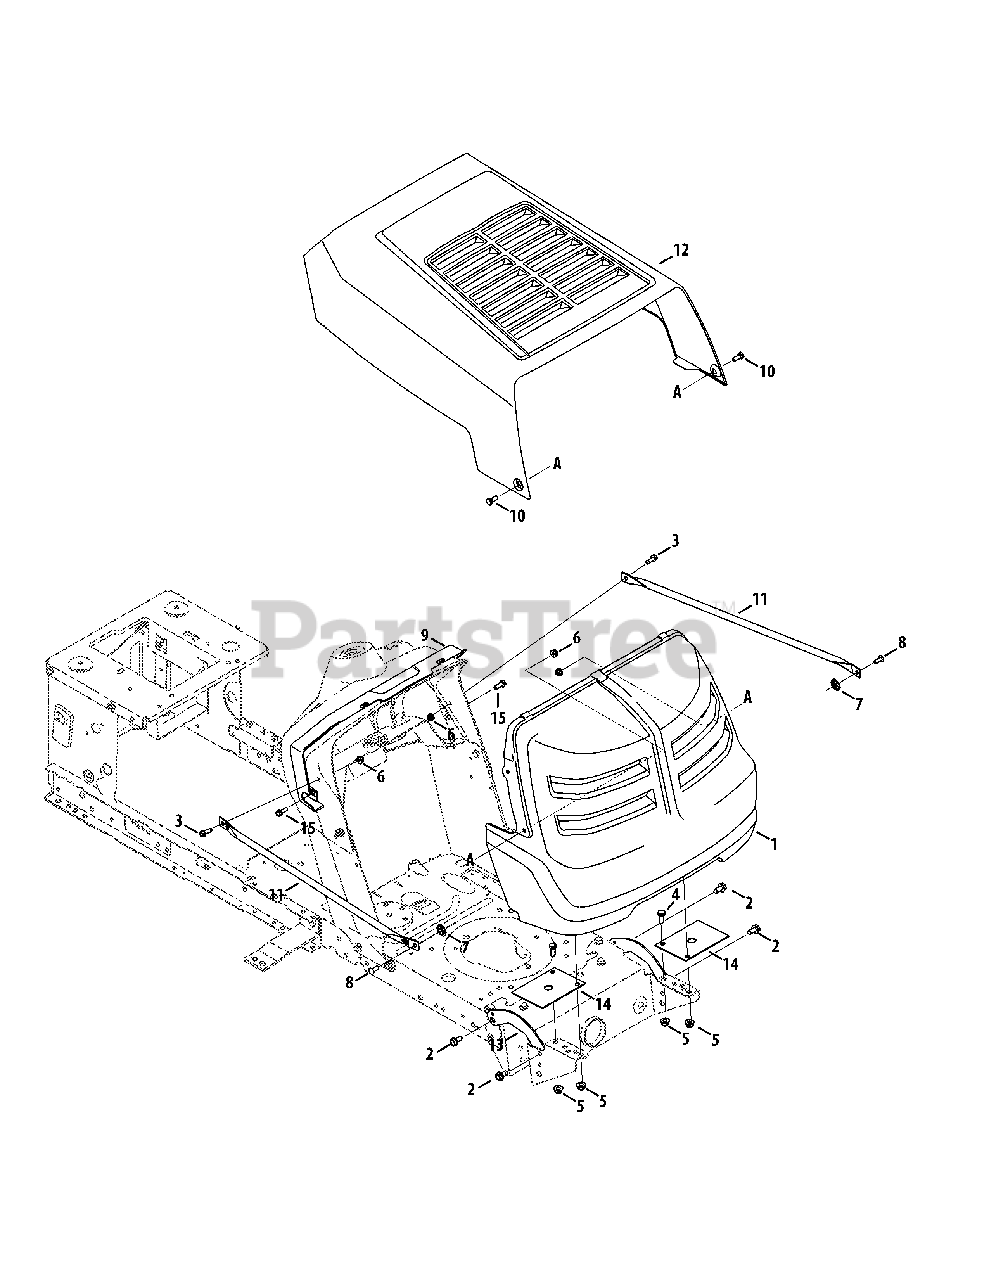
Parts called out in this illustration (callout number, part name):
1	Grill Assembly
2	Screw, Tap, 5/16-18, .750
3	Screw, Tap, 1/4-20, 0.750
4	Hex Screw, 5/16-18, .75
5	Flange Lock Nut, 5/16-18
6	Flange Lock Nut, 1/4-20
7	Nut, push-On, .25 Dia
8	Rivet, flat Head 1/4"
9	Collar, dash, 0/2 Style
10	Bolt, Shoulder, .375 X .125
11	Grill Support Rod
13	Front Pivot Support Bracket
14	Support Bracket
15	Screw, 1/4-15 x .750
